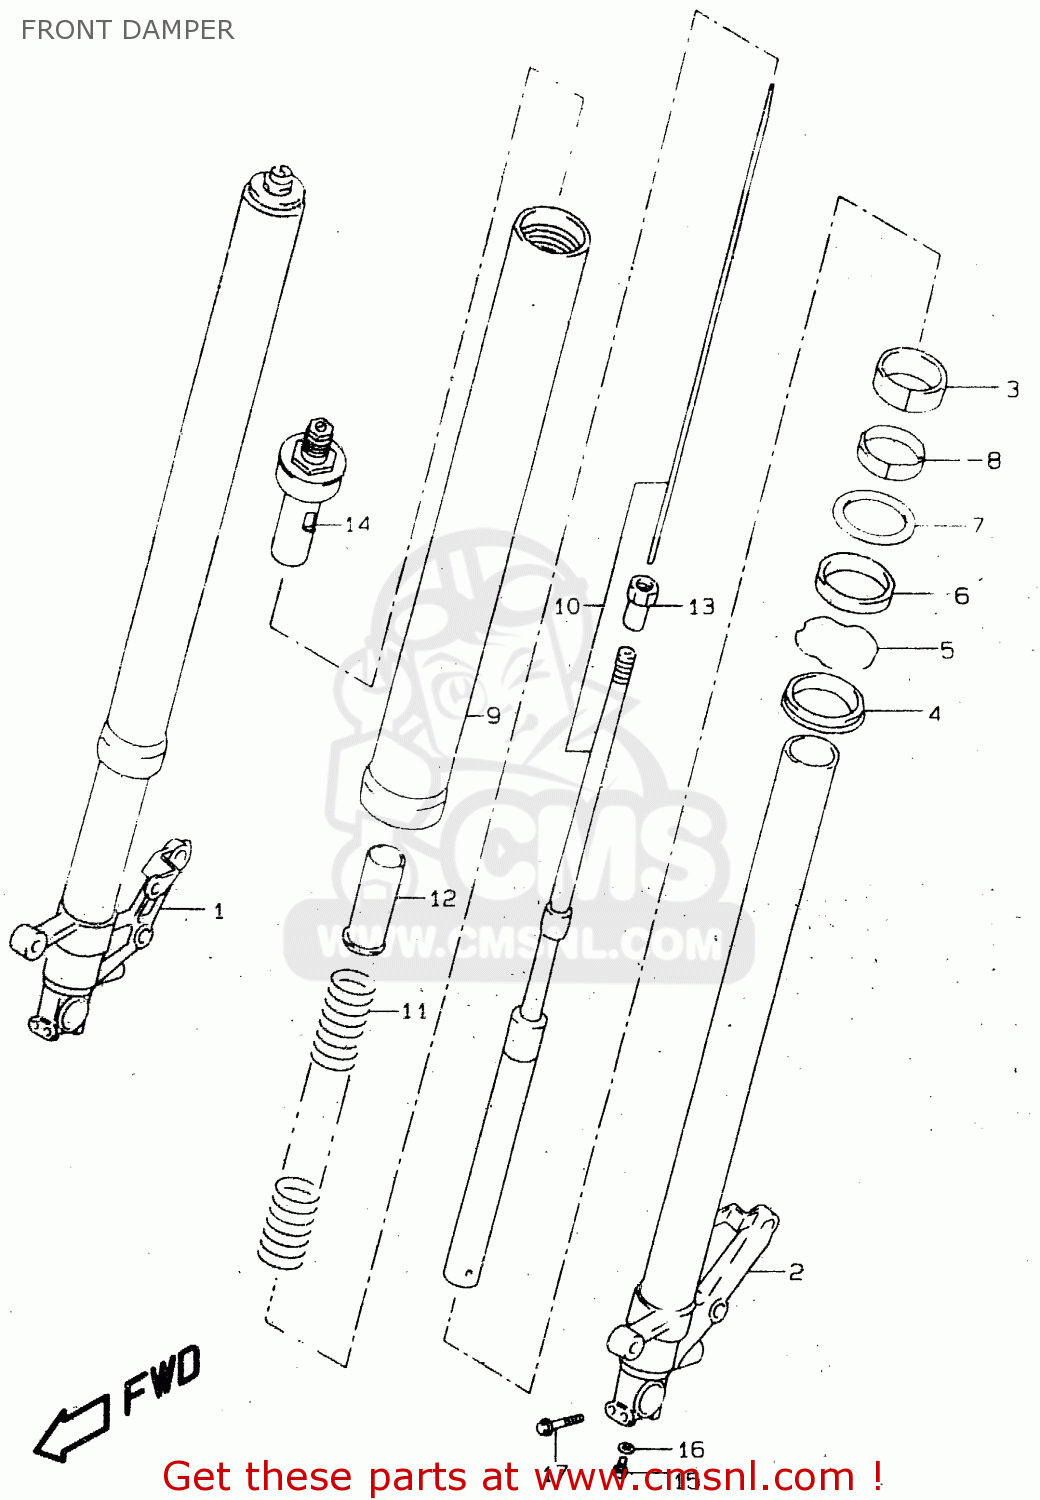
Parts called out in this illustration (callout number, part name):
1	TUBE,INNER,R
2	TUBE,INNER,L
3	PISTON
4	SEAL,DUST
5	RING,STOPPER
6	SEAL,OIL
7	WASHER
8	METAL,SLIDE
9	TUBE,OUTER
10	CYLINDER
11	SPRING,FR
12	SPACER,SPRING
13	NUT,PISTON ROD
14	CAP,FR FORK
15	BOLT,OIL LOCK PIECE,12X22
16	GASKET,CYLINDER (NAS)
17	BOLT
